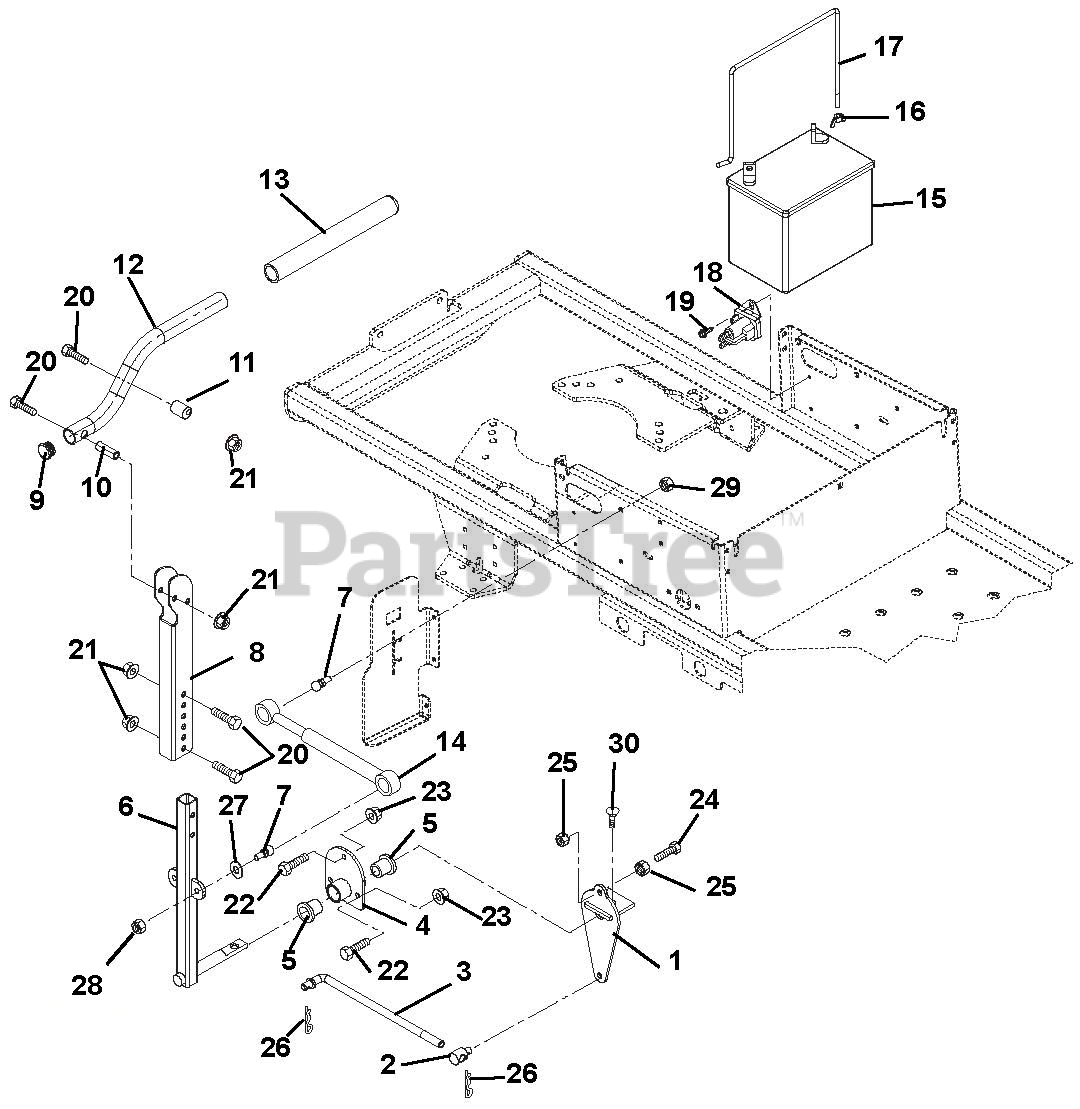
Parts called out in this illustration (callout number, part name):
1	Link, Control
2	Pivot, Rod
3	Link, Wireform
4	Weldment, Steering Bushing
5	Bushing, 1.00 x .75 x 1.00
6	Weldment, Control Arm
7	Stud, Ball
8	Channel, Upper Handlebar
9	Caplug, Handlebar
11	Eccentric
12	Handlebar
13	Grip, Handlebar
14	Damper, Control
16	Nut, Lock Wing .250-20
17	Battery Rod
18	Solenoid
19	Screw, Tap .250-20 x .37
20	Bolt, Hex .31-18 x 1.75 Grade 5
21	Nut, 5/16-18 Flange Nyloc
22	Bolt, Hex .31-18 x .75 Grade 5
23	Nut, Flange Nyloc 5/16 -18
24	Bolt, Hex .38-16 x 3.00 Grade 5
25	Nut, Spinlock Flange .375-16
26	Pin, Hair #25
27	Washer, Lock .31 x .078
28	Nut, Jam .312-18
29	Nut, Locking Top Flange .31-18
30	Bolt, 3/8 - 16 x 1.00 FSHCS Plain
